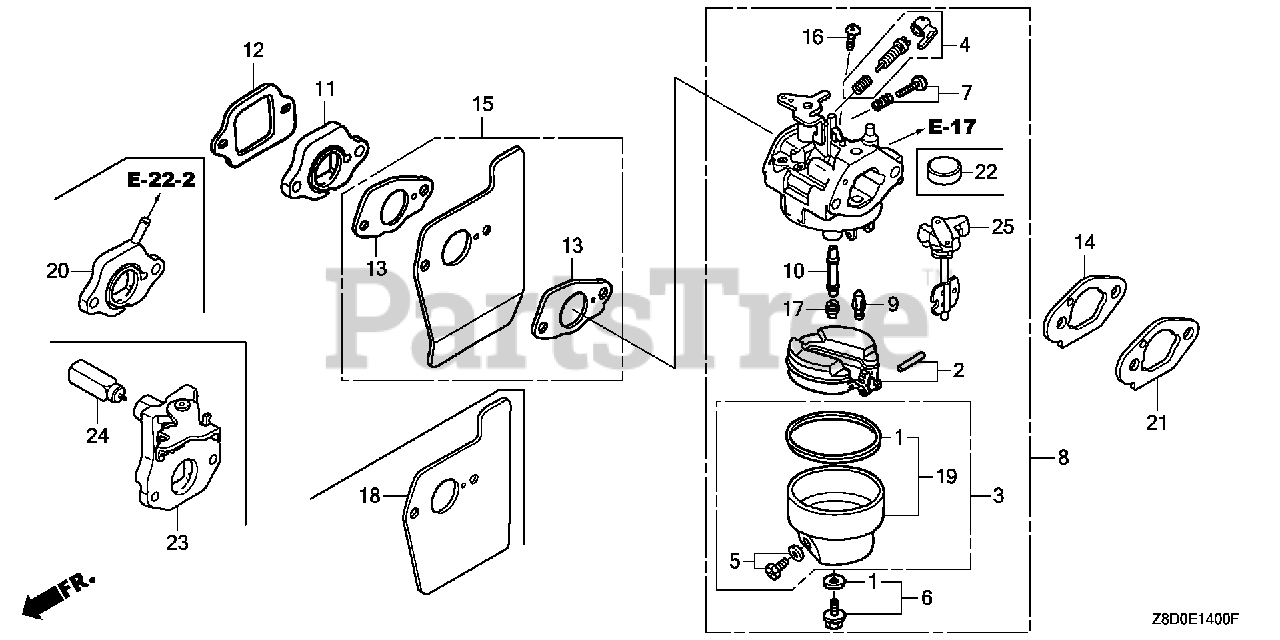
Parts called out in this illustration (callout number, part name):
1	GASKET SET
6	SCREW SET
8	CARBURETOR ASSY. (BB65M A)
8	CARBURETOR ASSY. (BB65M B)
8	CARBURETOR ASSY. (BB71A A)
9	VALVE, FLOAT
10	NOZZLE, MAIN (CARBURETOR NO.)
11	INSULATOR, CARBURETOR
12	GASKET, INSULATOR
14	GASKET, CARBURETOR
16	SCREW, PAN (5X6)
17	JET, MAIN (#62)
17	JET, MAIN (#65)
17	JET, MAIN (#68) (CARBURETOR NO.)
17	JET, MAIN (#70) (CARBURETOR NO.)
18	GUIDE, AIR
19	CHAMBER SET, FLOAT (CARBURETOR NO.)
21	SPACER, CARBURETOR
